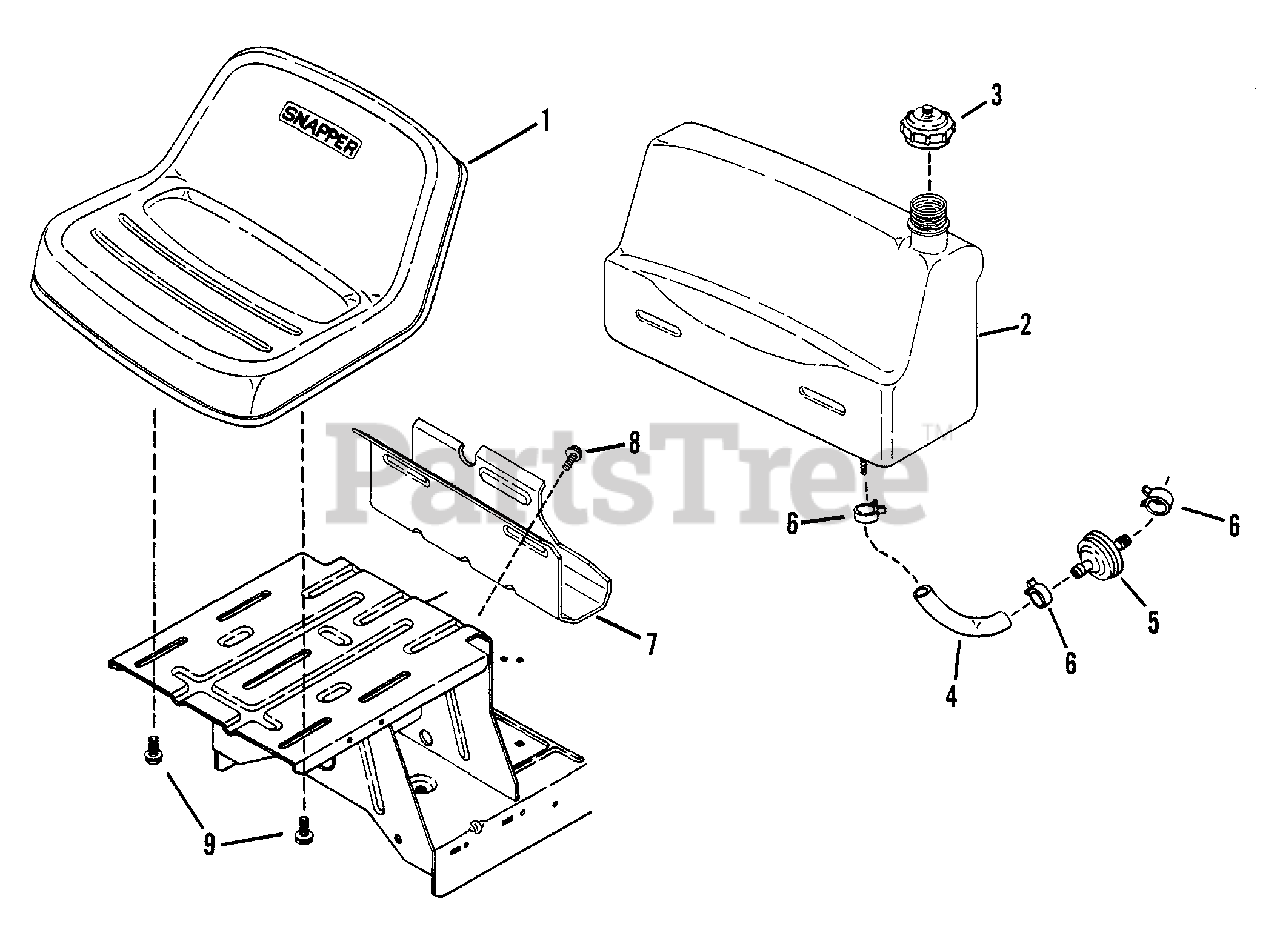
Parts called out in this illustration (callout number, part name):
1	SEAT, Operator
2	ASSEMBLY, Fuel Tank
3	CAP, Fuel Tank
4	HOSE, Fuel (7" Long)
4	HOSE, Fuel (5" Long)
4	HOSE, Fuel (8-1/2" Long)
5	FILTER, Fuel (In-Line)
6	CLAMP, Fuel Line
7	BRACKET, Fuel Tank (Rear)
8	SCREW, 5/16-18 x 5/8" Self-Tapping
9	BOLT, 5/16-18 x 1/2" Hex Flange Lock
